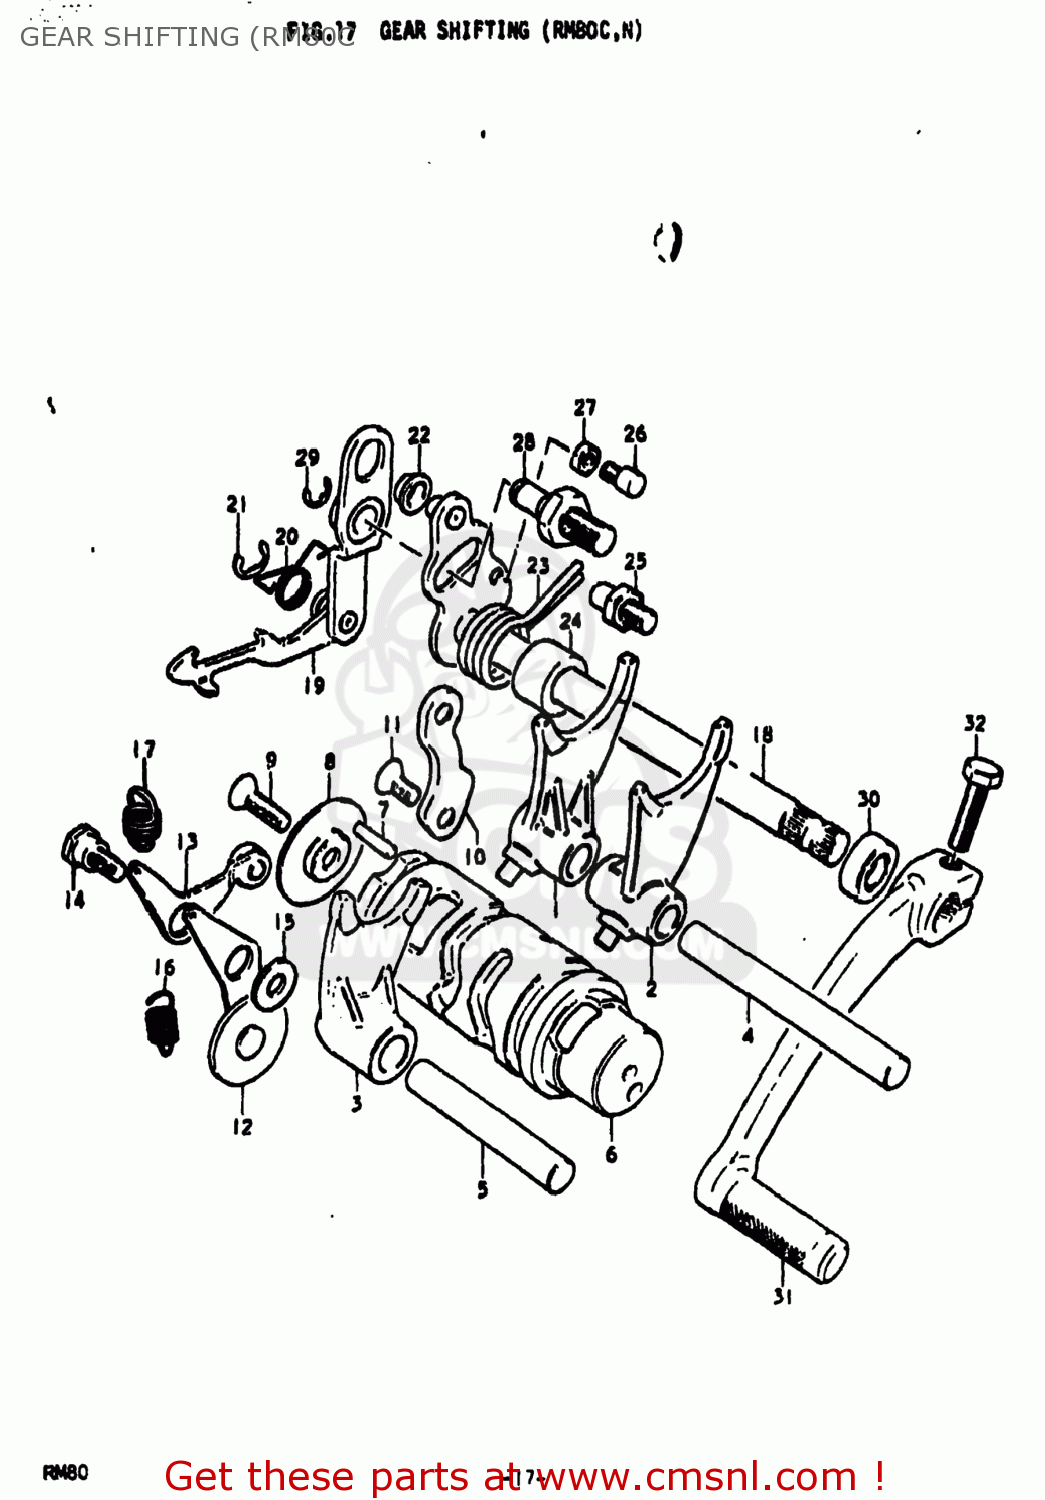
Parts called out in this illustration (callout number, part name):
1	FORK,GEAR SHIFT NO.1
2	FORK,GEAR SHIFT NO.2
3	FORK,GEAR SHIFT NO.3
4	SHAFT,GEAR SHIFT FORK
5	SHAFT,GEAR SHIFT FORK
6	CAM,GEAR SHIFT
7	PIN(4X15.8)
8	HOLDER,GEAR SHIFTING C
9	SCREW
10	GUIDE,GEAR SHIFTING CABLE
11	SCREW
12	STOPPER,GEAR SHIFTING
13	STOPPER,GEAR SHIFT CAM
14	BOLT(6X18.3)
15	WASHER (6.5X13X2.3)
16	SPRING
17	SPRING
18	SHAFT,GEAR SHIFT
19	PAWL,GEAR SHIFTING
20	SPRING
21	E RING
22	SPACER(7X10X5)
23	SPRING
24	SPACER(12X20X15.3)
25	STOPPER,GEAR SHIFT CAM
26	BOLT,GEAR SHAFT RETURN SPR SET
27	NUT 6MM
28	STOPPER,GEAR SHIFT CAM
29	E RING 6MM
30	OIL SEAL
31	LEVER ASSEMBLY,GEAR SHIFTING
32	BOLT
